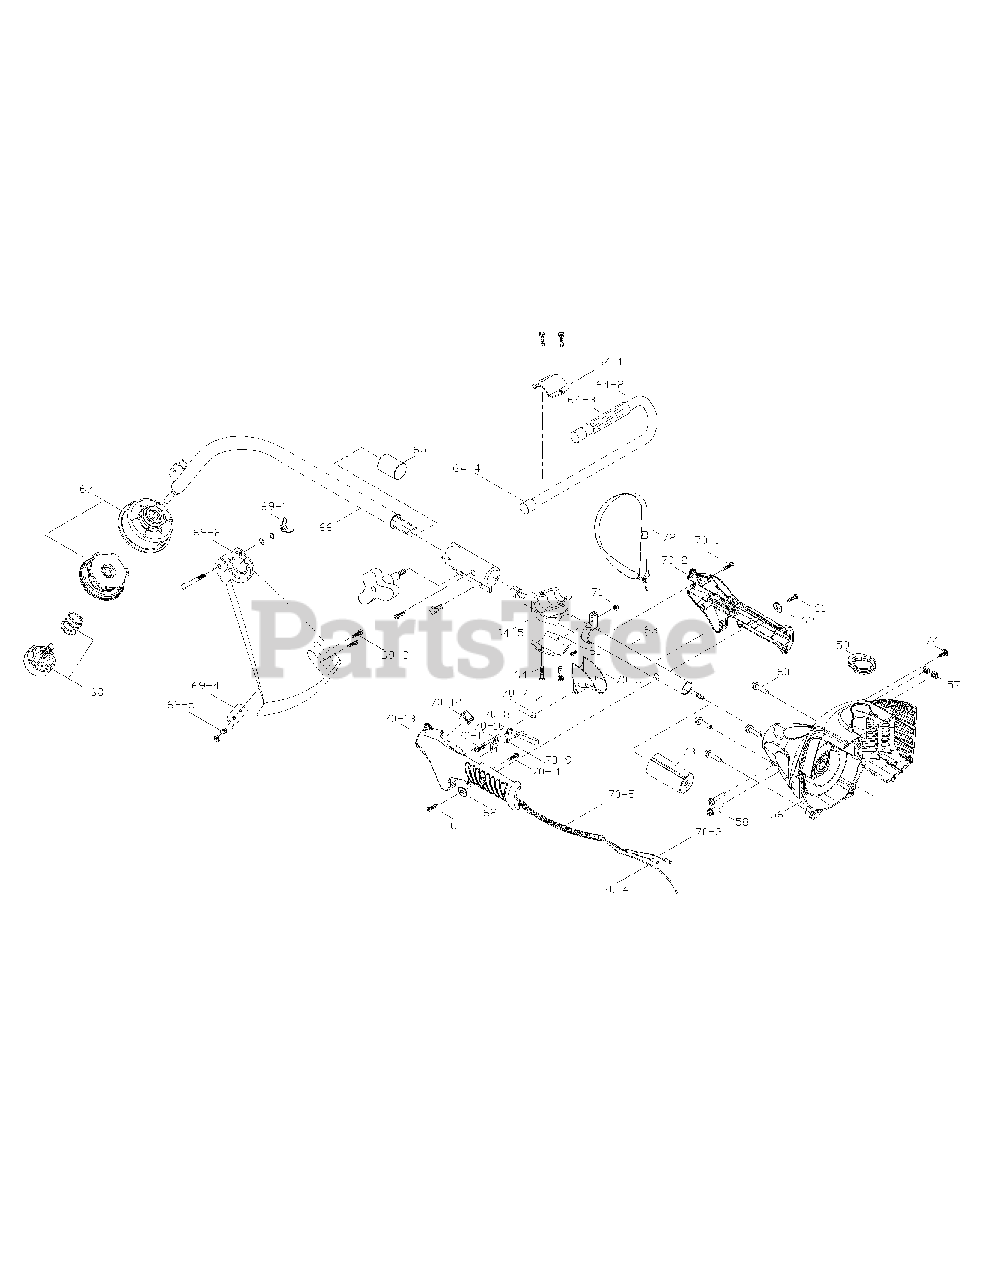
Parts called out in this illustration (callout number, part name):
1	SPARK PLUG
3	PLATE (SPARK SIDE)
7	MUFFLE ASS'Y
8	MUFFLE GASKET
9	MUFFLE PLATE
10	COVER (FLYWHEEL SIDE)
14	CYLINDER
16	PISTON RING
18	PISTON PIN
20	AXLS COVER
21	NEEDLE BEARING
23	CRANK/ROD ASS'Y
24	IGNITION COIL
26	COIL WIRE
28	STARTER HOUSING ASS'Y
29	PAWLS ASS'Y
30	KNOB
31	FILTER COVER
34	FILTER ASS'Y
35	CARBURETOR
36	CARBURETOR GASKET
40	INSULATOR
41	INSULATOR GASKET
43	CRANKCASE ASS'Y
43-1	CRANKCASE (STARTER SIDE)
43-3	CRANKCASE (FLYWHEEL SIDE)
47	C RING
49	FUEL TANK ASS'Y
51	NUT
53	CLUTCH (WITH SPRING)
54	WAVE PLATE
56	TRANSMISSION SUPPORT ASS'Y
63	BAG BEHIND
64	HANDLE ASS'Y
64-5	CENTERPLECE
64-6	PARTS BAG
66	BAG FRONT
67	STRINGHEAD ASS'Y
68	KNOB ASS'Y
69	COVER ASS'Y
69-1	PARTS BAG
69-4	KIT, KNIFE
70	HANDLE ASS'Y
70-2	HOUSING, HANDLE
70-3	WIRE ASS'Y, SWITCH
70-4	THROTTLE CABLE
70-8	LIBERATE SHAFT
70-10	LIBERATE CHUNK
70-13	HOUSING, HANDLE
71	NUT
